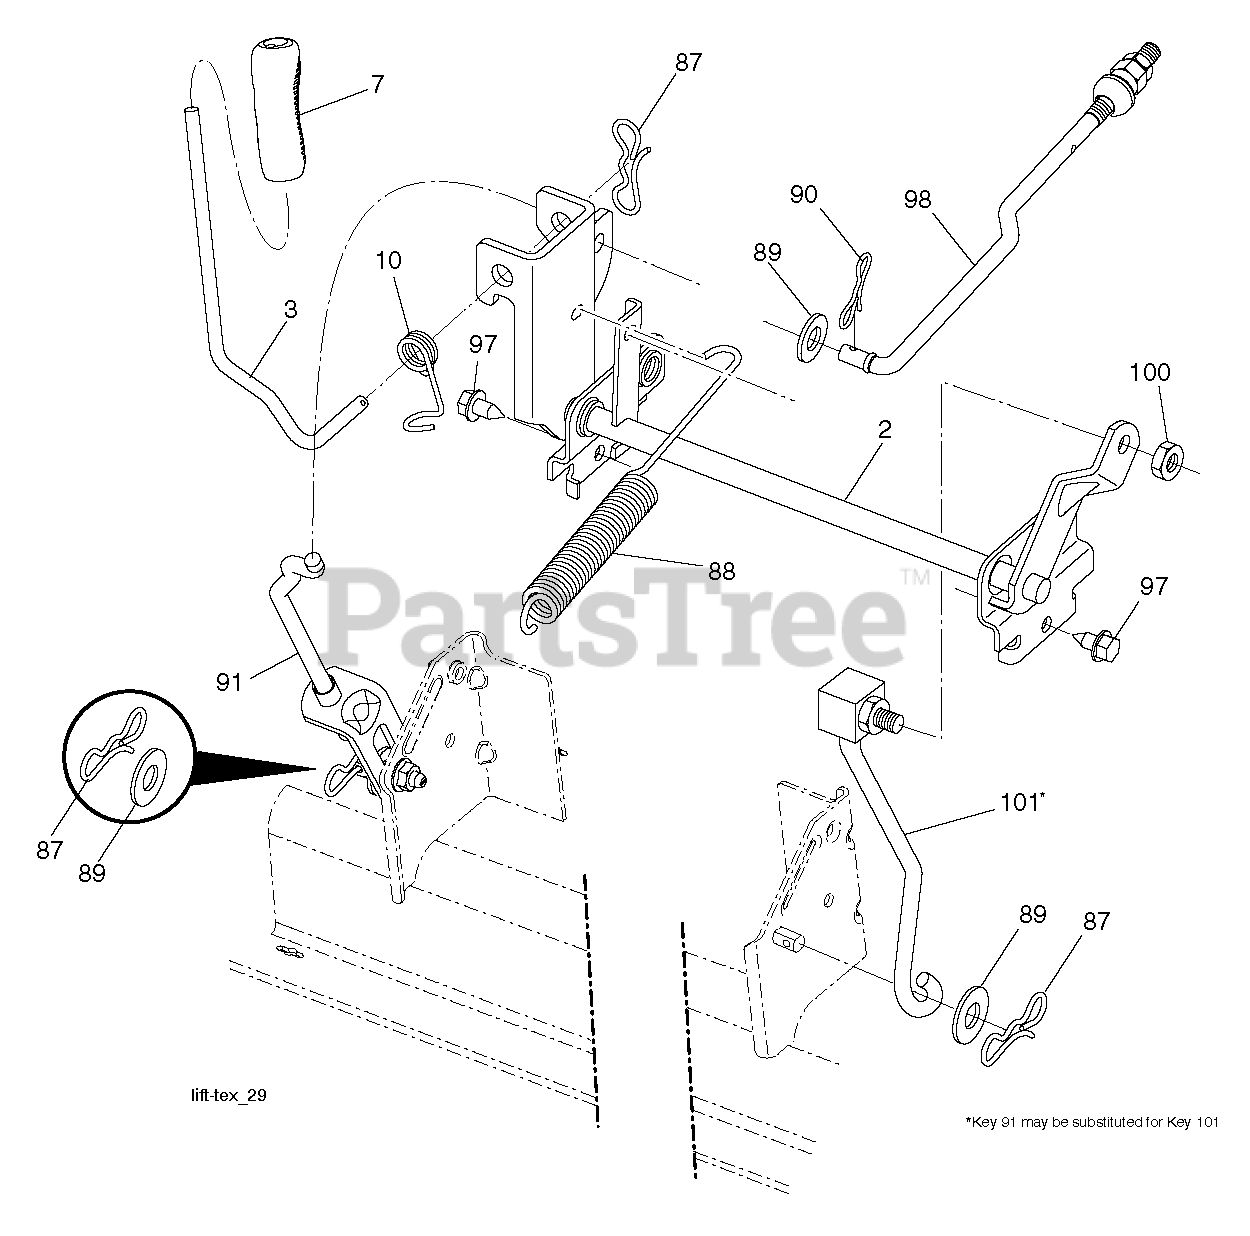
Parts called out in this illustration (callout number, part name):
2	SHAFT.ASM.CROSS.LIFT
3	LEVER.LIFT.HANDLE.LT
7	GRIP.HANDLE.LIFT.PVC.BLACK
10	SPRING.TORSION.LIFT.HANDLE
87	PIN.COTTER.7/16.BOW TI.
88	SPRING.LIFT.ASSIST
89	WASHER.CLEAR.ZINC
90	PIN.COTTER.5/16.BOW TI
91	LINK.LIFT.ASM.REAR.GT.
97	SCREW, 3/8-16X3/4
98	LINK.ASSY.FRONT.MWR.SUSP
100	LOCKNUT
101	LINK.ASSY.BLACK.431
